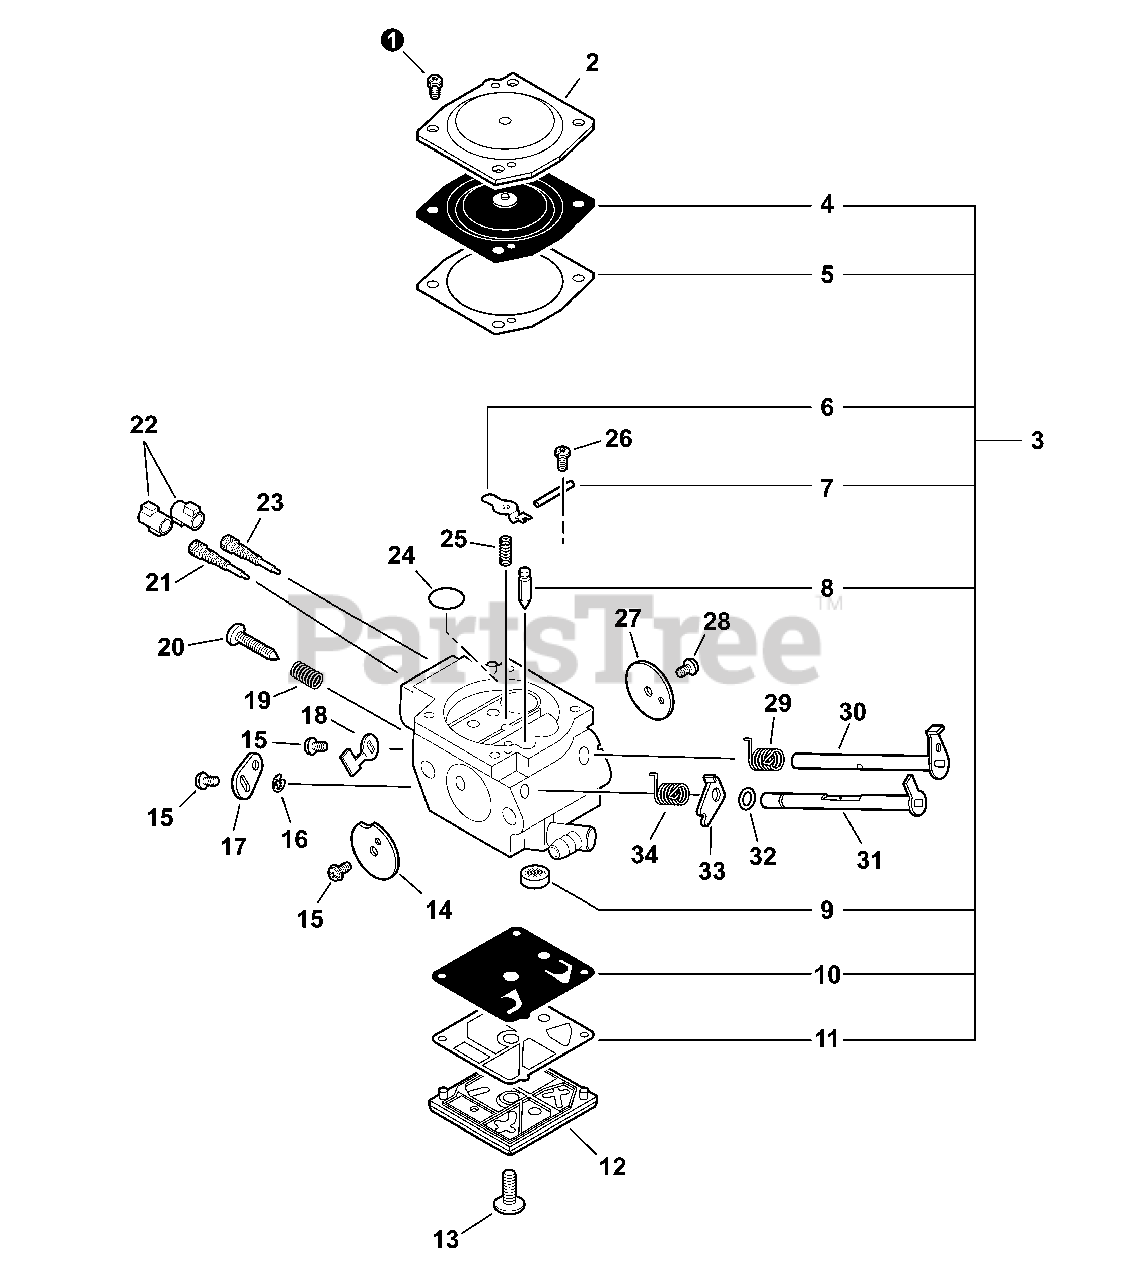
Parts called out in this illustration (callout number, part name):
2	COVER, DIAPHRAGM
3	REPAIR KIT
4	DIAPHRAGM, METERING
5	GASKET, METERING
6	LEVER, METERING
7	PIN, METERING LEVER
8	VALVE, INLET NEEDLE
9	STRAINER
10	DIAPHRAGM, PUMP
11	GASKET, PUMP
12	COVER, PUMP
14	VALVE, CHOKE
16	RING, RETAINING
17	LEVER, CHOKE
18	STOP, THROTTLE
19	SPRING, IDLE ADJUST
20	SCREW, IDLE ADJUST
21	NEEDLE - HIGH SPEED
22	CAP, LIMITER
23	NEEDLE - LOW SPEED
24	PLUG, WELCH
25	SPRING, METERING LEVER
26	SCREW, METERING LEVER PIN
27	VALVE, THROTTLE
28	SCREW, THROTTLE VALVE
29	SPRING, THROTTLE RETURN
30	SHAFT, THROTTLE
31	SHAFT, CHOKE
33	LEVER, FAST IDLE
34	SPRING, CHOKE RETURN
